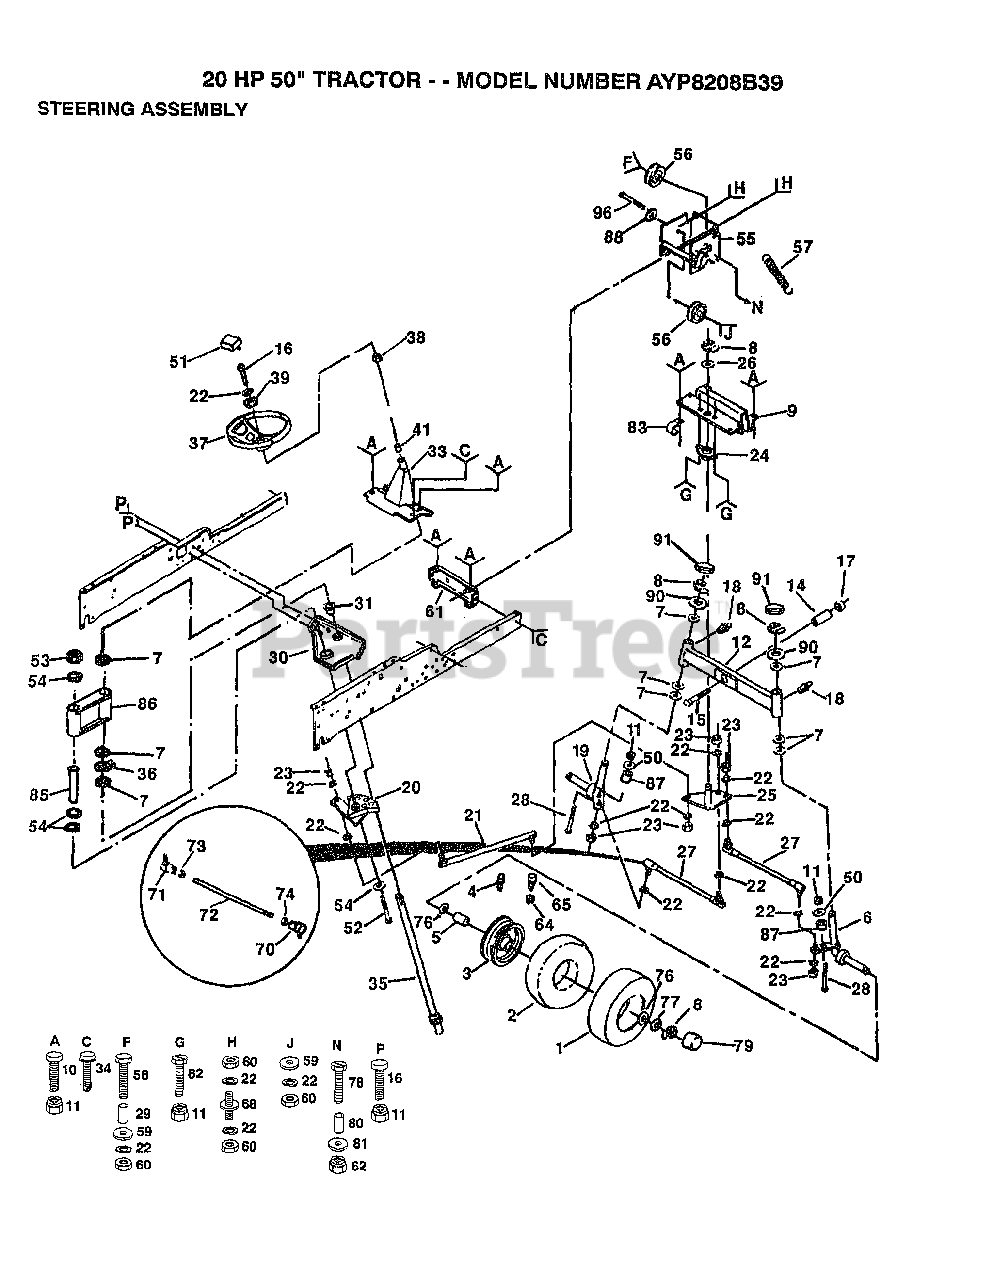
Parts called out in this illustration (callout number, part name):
2	TUBE.16X6.5/7.5-8
4	FITTING LT
5	"FLANGE, BEARING"
6	SPINDLE RH T
7	WASHER .T
8	RING
9	AXLE BRACKET T
14	SPACER BEARING
15	BOLT
16	BOLT
17	LOCKNUT M
18	ZERK M
19	SPINDLE ASSY T
20	SECTOR T
21	LINK.DRAG.T
22	LOCKWASHER
25	"T, BELLCRANK"
26	WASHER
27	TIE ROD T
28	BOLT
29	SPLIT SPACER YTV
31	"FLANGE GT, BEAR."
33	SUPPORT ASSY T
34	SCREW
35	SHAFT STEERING GT
36	KLIP RING
38	ADAPTER LT
39	WASHER T
41	"T, BEARING"
50	WASHER T
51	"INSERT,STR WHEEL"
52	BOLT T
53	NUT LTV
54	WASHER GT
55	IDLER BRKT T
56	IDLER-INSIDE T
57	SPRING
58	BOLT
59	WASHER
60	NUT.HEX.3/8-16UNC
61	FRAME BRACKET GT
64	VALVE STEM LT
65	VALVE CAP
70	JOINT.RH
71	JOINT.LH
73	NUT
74	NUT
76	WASHER
77	WASHER
79	HUB CAP
80	BUSHING LT
81	WASHER
82	BOLT
83	CLIP GTV
85	TUBE T
86	COLLAR
87	SPACER LT
88	WASHER T
90	WASHER
91	CAP
